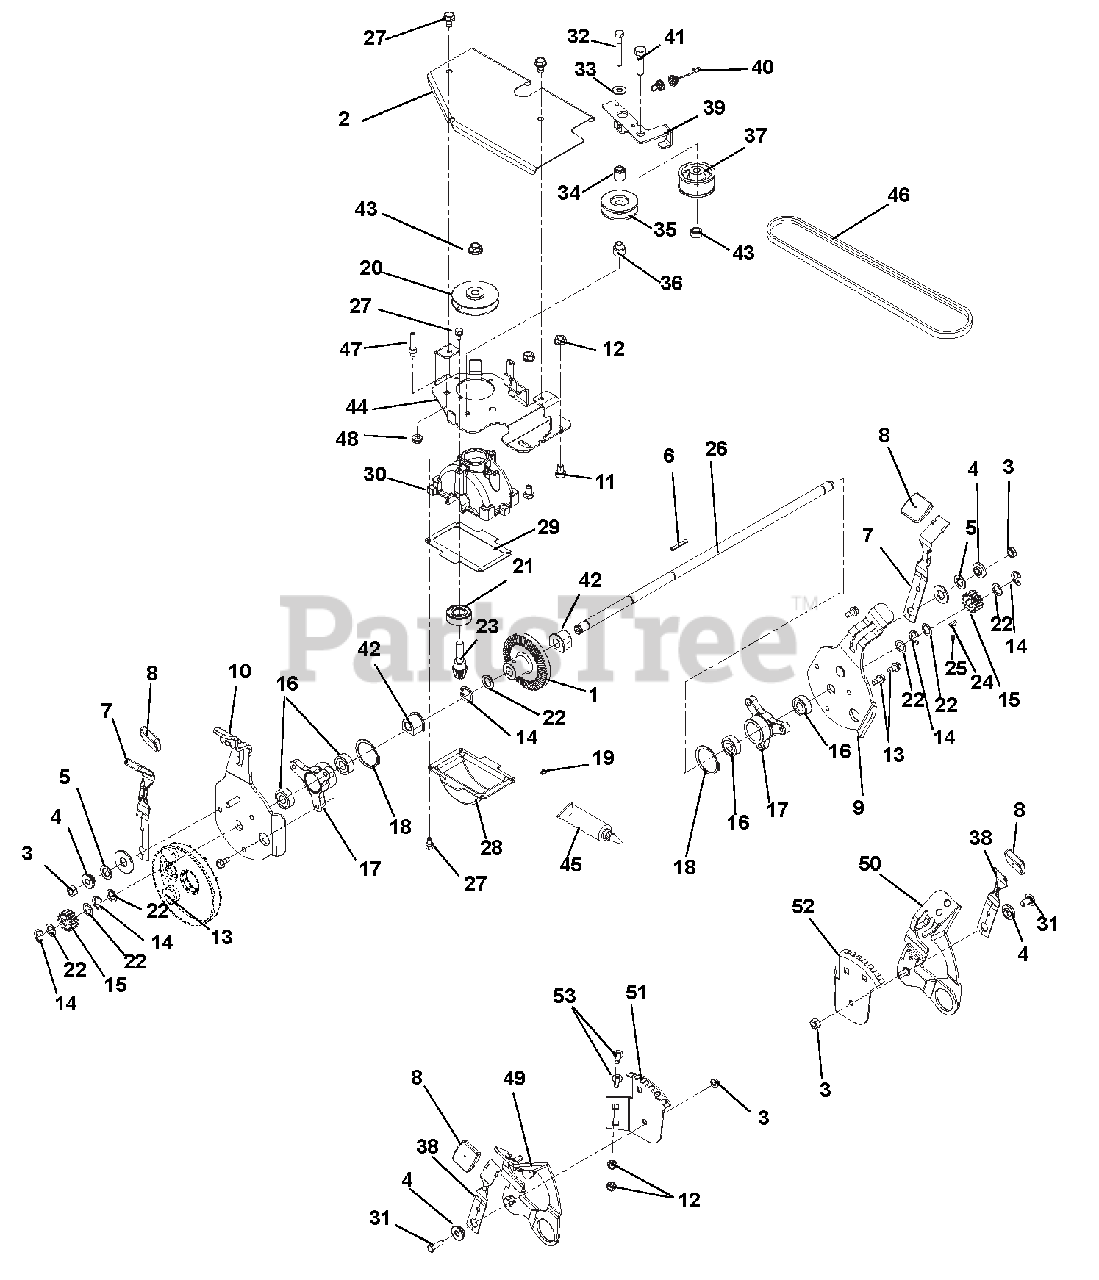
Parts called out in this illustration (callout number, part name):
1	GEAR, BEVEL (CU INFL, KEYWAY)
2	COVER, TRANSMISSION
3	@NUT-LK-CTR .31-18 YWZC
4	BSHG-FLG .32X.500X.344X.880
5	WSHR-FL-STL .52X.827X.062 YWZC
6	KEY, 1/8 X 1/8 X 1.0
7	LEVER, HEIGHT ADJUSTMENT
9	WLDMT, HEIGHT ADJUSTER RHS
10	WLDMT, HEIGHT ADJUSTER LHS
11	@BLT-HEX .31-18X.50 GR5 YWZC
12	@NUT-LK-TOP-FLG .31-18 YWZC
13	SCR-TAP .25-20X.50 HWH TR YWZ
14	RG-RTNG-EXT.50 X .034
15	PINION-WBLM DRIVE
16	BEARING, .500X1.125X.375
17	BUSHING, HEIGHT ADJUSTER PIVOT
18	RG-RTNG-EXT 1.387X.050
19	FTG-LUBE .25-28X.256 YWZC
20	PULLEY, TRANS INPUT
21	BRG-BALL .625X1.375X.43
22	WASHER, .500X.750X.020 THRUST
23	PINION, GEARBOX INPUT
24	KEY-WDRF .125X.50X.20 (HRDEND)
25	SPRING, .134X.180X.144 COMP.
26	SHAFT, TRANS COMMERCIAL 21
27	SCR-TAP 10-24X.375 PRE-COAT 80
28	SUMP, GEARBOX - XD
29	GASKET, TRANSMISSION
30	HOUSING, WBLM GEAR BOX
31	@BLT-HEX .31-18X1.00 GR5 YWZC
32	BLT-HEX .25-20X2.25 GR8 YWZC
33	@WSHR-FL-STL.312X.734X.065 YWZ
34	SPACER, IDLER ARM
35	IDLER, 3L FRONT SIDE .38X1.875
36	SPACER, V-IDLER PULLEY
37	IDLER - FLAT 1.875OD X .75WIDE
38	FRONT HEIGHT ADJUSTMENT LEVER
39	ARM-TRANS IDLER
40	SG-TENS .051X.60X2.25 WLD 7.0
41	@BLT-HEX .38-16X1.25 GR5 YWZC
42	BUSHING, TRANS OUTPUT SHAFT
43	@NUT-LK-TOP-FLG .38-16 YWZC
44	BRKT, TRANSMISSION MOUNT
45	LUBRICATE
46	V-BELT, 3L-WRAPPED
47	FINGER, BELT
48	@NUT-SPNLK-FLG .25-20 YWZC
49	RH ADJUSTER BRACKET
50	LH ADJUSTER BRACKET
51	FRONT QUADRANT, R.H.
52	FRONT QUADRANT, L.H.
53	@BLT-RHDSSQNK .31-18X1.00 G5YZ
